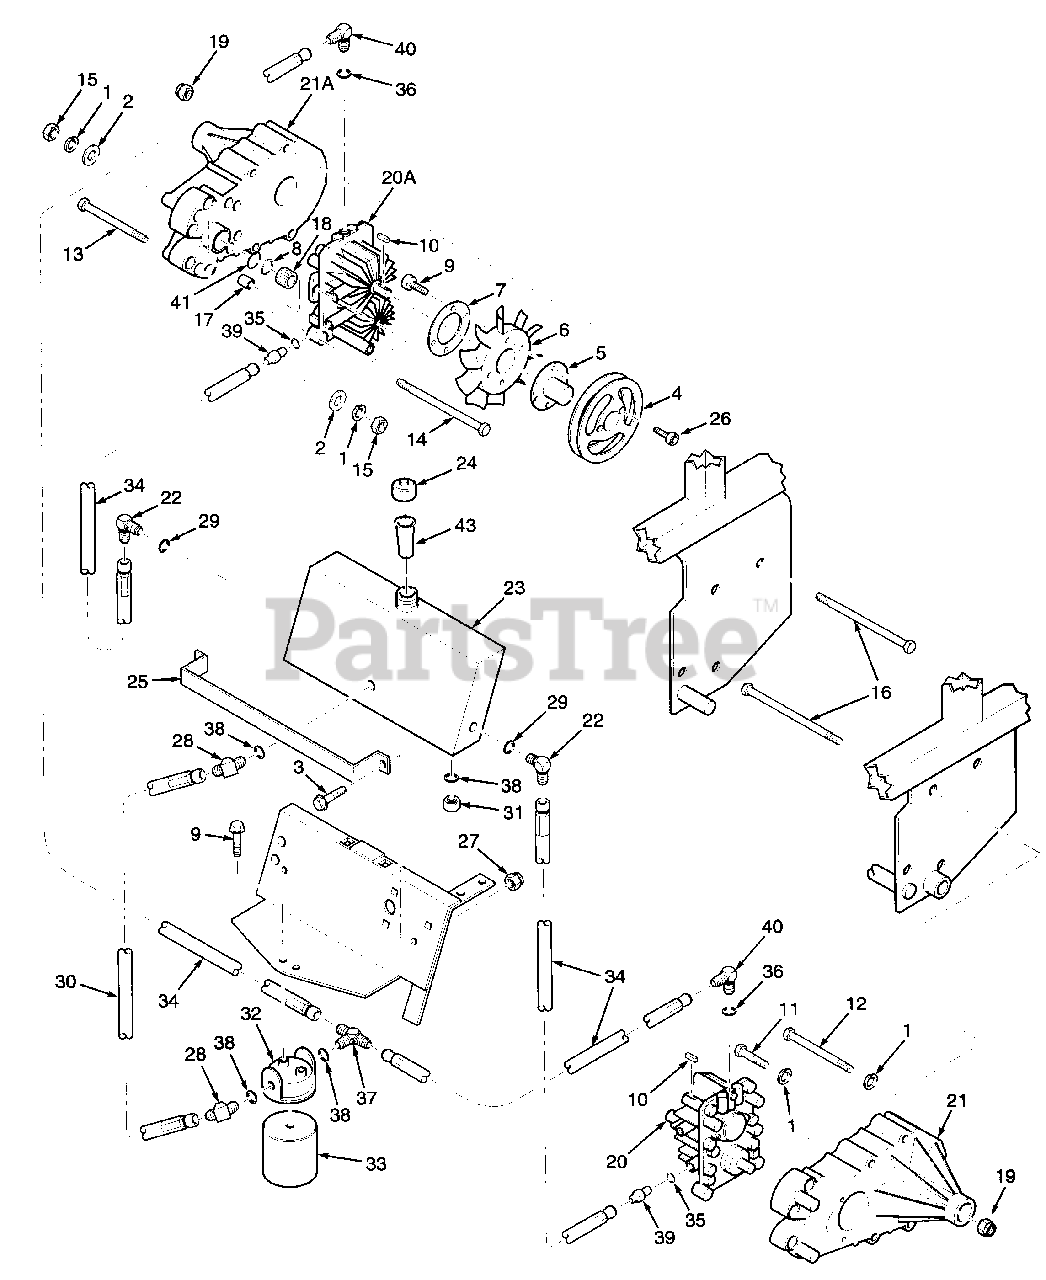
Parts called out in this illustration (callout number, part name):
1	Lockwasher, 5/16"
2	Flatwasher, 5/16" (.344 x .688 x .065)
3	Bolt, Serrated Flange Hex Head 1/4 x 20 x 3/4"
4	Pump, Pulley
5	Tapered Hub, 15 mm Bore
6	Fan
7	Washer, Back-up
8	Snap Ring
9	Capscrew 1/4-20 x 1/2"
10	Key, 5 mm x 5 mm x 25 mm
11	Bolt, Hex Head 5/16-18 x 1-3/4"
12	Bolt, Hex Head 5/16-18 x 4-1/2"
13	Bolt, Hex Head 5/16-18 x 5"
14	Bolt, Hex Head 5/16-18 x 7-1/2"
15	Nut, Hex 5/16-18
16	Bolt, Hex Head 3/8-16 x 4", grade 8 black
17	Spacer
18	Gear
19	Nut, Elastic Stop 3/8-16, grade 8 black
20	Pump, LH
20A	Pump, RH
21	Axle, LH
21A	Axle, RH
22	Elbow, 90 Degree 9/16-18 JIC to 9/16-18 "O" Ring
23	Oil Tank Reservoir
24	Cap, Oil Reservoir
25	Strap, Oil Reservoir
26	Screw, Socket Hex Cap 1/4-20 x 1-3/8"
27	Nut, Elastic Stop 1/4-20
28	Elbow, 45 Degree 3/4-16 JIC to 3/4-16 "O" Ring
29	"O" Ring, 5/64 x 15/32 ID
30	Hose Assembly, Filter Inlet
31	Plug, 3/4-16 "O" Ring
32	Head, Oil Filter
33	Oil Filter, Special
34	Hose Assembly
35	"O" Ring, 3/32 x 3/4 ID
36	"O" Ring, 1/16 x 3/8 ID
37	1/2" T-fitting, 3/4-16 JIC to 3/4-16 "O" Ring
38	"O" Ring, 3/32 x 5/8 ID
39	Tube Union 3/4-16 JIC to 7/8-14 "O" Ring
40	Elbow, 90 Degree 9/16-18 JIC to 7/16-20 "O" Ring
41	"O" Ring
43	Filler Neck Insert
